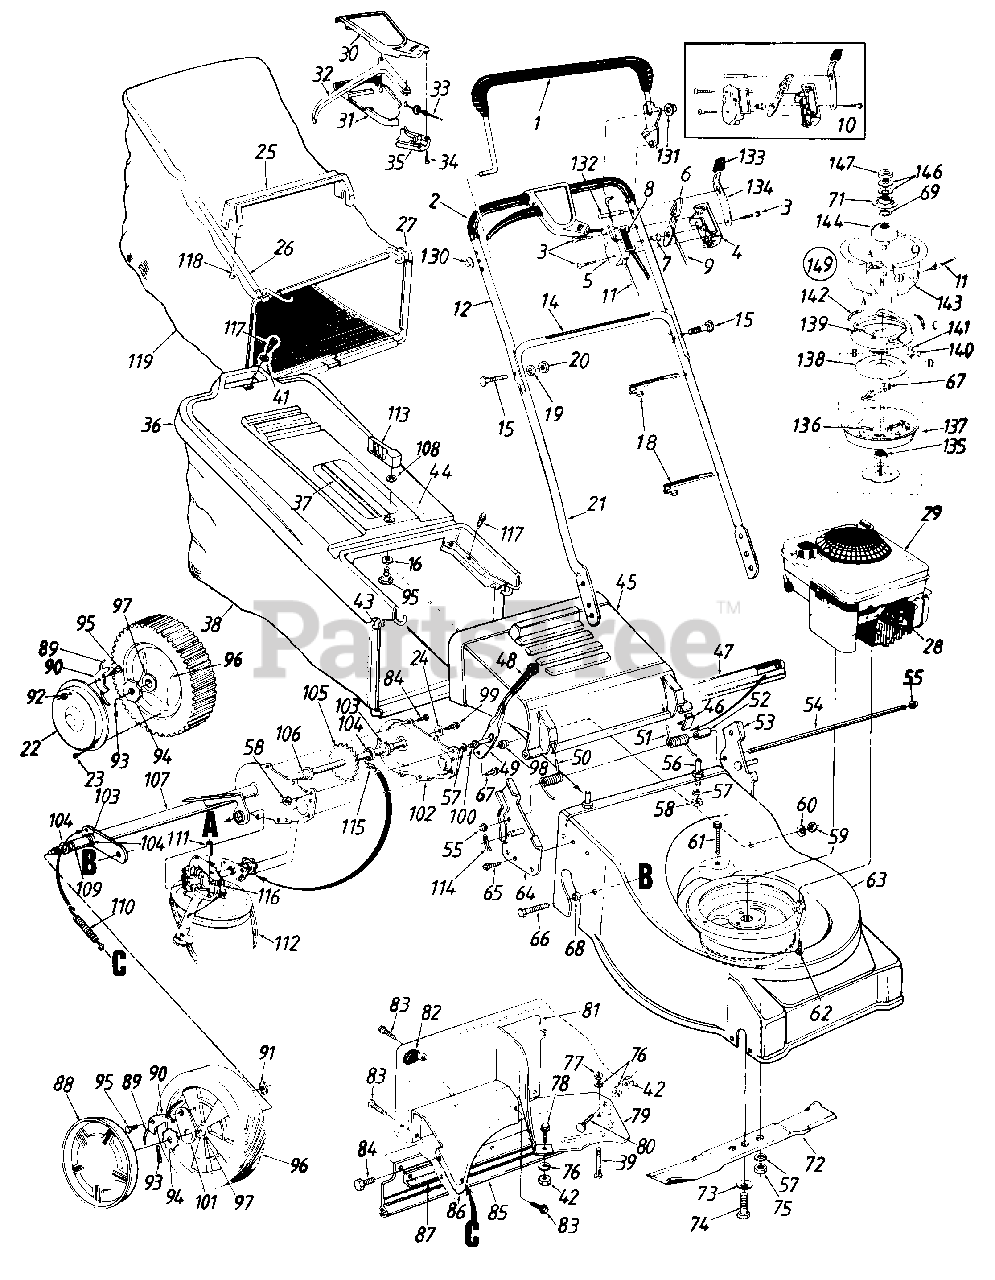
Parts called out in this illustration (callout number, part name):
1	Control Handle Ass'y.
2	Grip
3	Truss Mach. B-Tap Scr. #12 x 1.5" Lg.
4	Control Panel Half
5	Clutch Panel Half
6	Throttle Control Lever
7	Control Disc Pin
8	Control Label-Throttle
9	Throttle Wire-58" Lg.
10	Control Housing Comp.
11	Control Cable -52" Lg.
12	Upper Handle
14	Instruction Label-Handle
15	Curved Carriage Bolt 5/16-18 x 1.38" Lg.
16	Bowed Washer
18	Cable Tie
19	L-Wash. 5/16" I.D.
20	Hex Nut 5/16-18 Thd.*
21	Lower Handle
22	Hub Cap
23	Pan Hd. Tap Scr. #12 x .50" Lg.
24	Bell-Wash. .265" I.D. x .75
25	Bag Handle
27	Front Catcher Frame
28	Spark Plug Boot
29	Engine
30	Control Cover Half-Upper
31	Control Cover Half-Lower
32	Control Lever
33	Drive Cable-53" Lg.
34	Flat C-Sunk Hd. Tap Scr. #10 x .75" Lg.
35	Cable Mtg. Cap
36	Hardtop Bag Cover
37	Hardtop Handle
38	Grass Bag
39	Truss Mach. Scr. 1/4-20 x 1.0" Lg.
41	Fl-Wash. .281" I.D. x .62"
42	Hex Nut 1/4-20 Thd.*
43	Front Catcher Frame
46	Deflector Plug
47	Seal-Extrusion
49	Spring Lever
50	Torsion Spring-R.H.
51	Torsion Spring-L.H.
52	Spacer.255" I.D.
53	Handle Brkt. Ass'y.-L.H.
54	Hinge Pin 17.75" Lg.
55	Cap Speed Nut
56	Shld. Pin 3/8-24 x 1.43" Lg.
57	L-Wash. 3/8" I.D.*
58	Hex Jam Nut 3/8-24 Thd.
59	Hex L-Nut 3/8-24 Thd.
60	Bell-Wash. .38" I.D. x .88"
61	Hex Wash. Hd. Tap Scr. 1/4-20 x 1.5" Lg.
62	Hex L-Wash. Hd. Scr. 3/8-16 x 1.0" Lg.
63	21" Deck Ass'y.
64	Handle Brkt. Ass'y.-R.H.
65	Hex L-Wash. Hd. AB-Tap Scr. 1/4 x.62" Lg.
66	Hex Wash. Hd. Tap Scr. 3/8-16 x . 75 " Lg .
67	Hex Wash. Hd. Tap Scr. 1/4 -20 x .5" Lg .
68	Spacer.383" I.D.
69	Serrated Washer 1.0" I.D.
71	Serrated Pulley Half
72	21 " Blade
73	Bell-Wash. .46" I.D. x .88"
74	Hex Bolt 7/16-20 x 2.0" Lg. (Grade 5)
75	Hex Nut 3/8-24 Thd. (Grade 8)
76	L-Wash. 1/4" I.D.
77	Hex Jam Nut 1/4-20 Thd.
78	Hex Bolt 1/4-20 x .85" Lg.
79	Rear Belt Baffle
80	Carr. Bolt 1/4-20 x .50" Lg.
83	Torx Mach. AB-Tap Scr. 1/4 x .62" Lg.
84	Hex B-Tap Scr. 1/4 x .38" Lg.
85	Rear Flap
89	Plastic Spring
90	Pawl.345" I.D.
91	Weld Nut 1/4-20 Thd.
92	Hex Ins. L-Nut 1/4-20 Thd.
93	Cotter Pin 1/8" Dia.
94	Ratchet Wheel 1.62" O.D.
95	Shld. Bolt .342" Dia. x .268"
96	Wheel Ass'y. Comp.-Rear
97	Flange Ball Bearing 1/2" I.D.
98	Shld. Spacer .50" Dia.
99	Hex Bolt 1/4-20 x .62" Lg. (Grade 5)
100	Shld. Pin 3/8-24 x 1.43" Lg.
101	Pawl Plate
104	Fl-Wash. .531" I.D. x .93"
105	Rear Axle Ass'y.
106	Hex Flange Bearing
109	Spacer. 513" I.D.
110	Extension Spring 3.8" Lg.
111	Spacer.325" I.D.
112	V-Belt
113	Grass Catcher Locking Knob
114	Internal Cotter Pin 5/16" Dia.
115	#48 Chain .50" Pitch x 30 Links
116	Transmission Comp.
117	Hex L-Wash. Hd. AB-Tap Scr. 1/4 x .62" Lg.
118	Hex AB-Tap Scr. #12 x 1.25" Lg.
119	Grass Bag
130	Push Cap
131	Push Cap
132	Lock Pin .314" Dia. x 1.75"
133	Spring Lever Knob
134	Lockout Spring
135	Ball Brg. .669" I.D. x 1.574"
136	Comp. Spring .35" O.D. x 2.0" Lg.
137	Clutch Blade Housing Ass'y.
138	Clutch Cone
139	Brake Cup Cone
140	Ball Block
141	Steel Ball .50" Dia.
142	Ext. Spring 1.75" Lg.
143	Clutch Housing
144	Fixed Pulley Adapter
146	Bell-Wash. 1.01" I.D.
147	Crankshaft Spacer
149	Blade Brake Clutch Ass'y. Comp.
